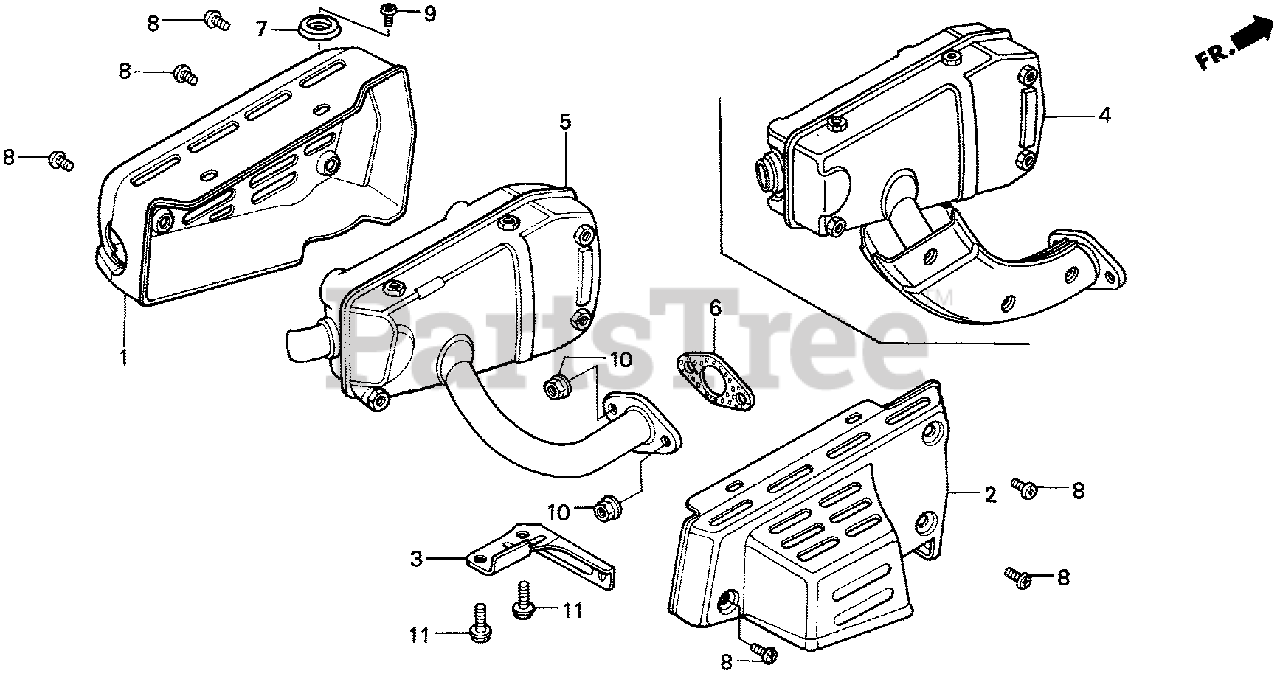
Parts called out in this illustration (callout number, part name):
1	PROTECTOR, MUFFLER
2	SEPARATOR, MUFFLER
3	STAY, MUFFLER
6	GASKET, MUFFLER
7	WASHER, MUFFLER
8	SCREW, PAN (6X6)
9	SCREW, PAN (6X8)
10	NUT, FLANGE (8MM)
11	BOLT, FLANGE (6X16)
